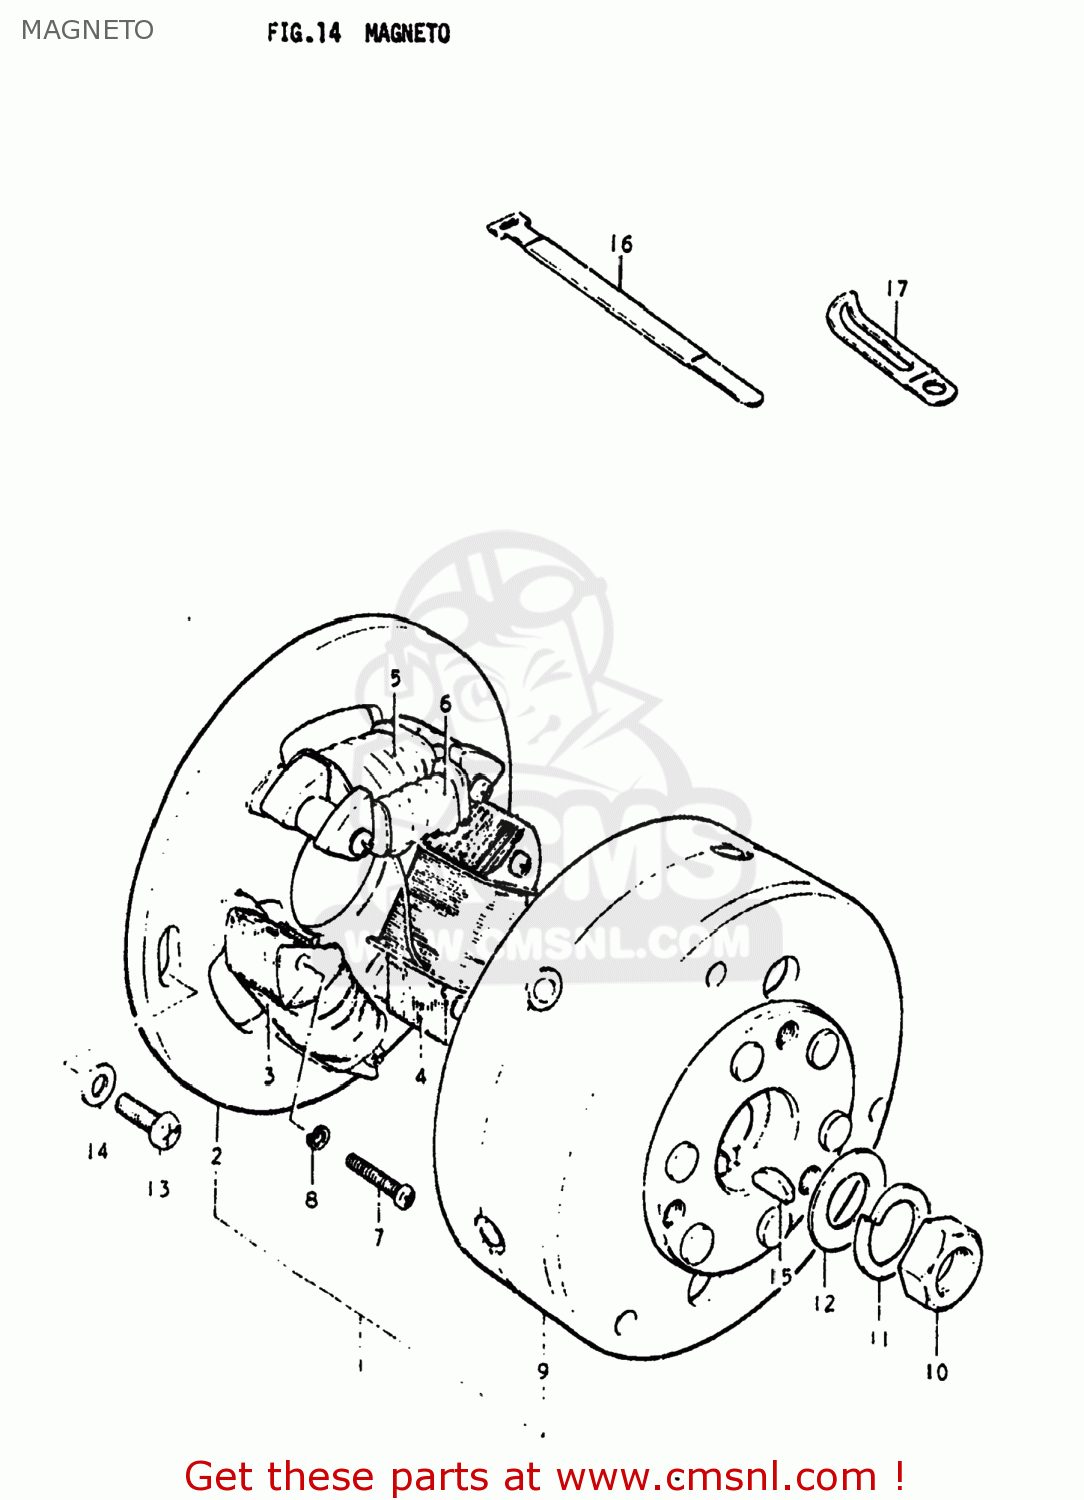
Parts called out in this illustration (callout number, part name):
1	MAGNETO ASSEMBLY
2	STATOR ASSEMBLY
3	COIL,LIGHTING
4	COIL
5	COIL
6	COIL,PULSER
7	SCREW
8	LOCK WASHER
9	ROTOR ASSEMBLY
10	NUT (10MM)
11	LOCK WASHER
12	WASHER
13	SCREW
14	WASHER
15	KEY 4MM
16	CLAMP
17	CLAMP
